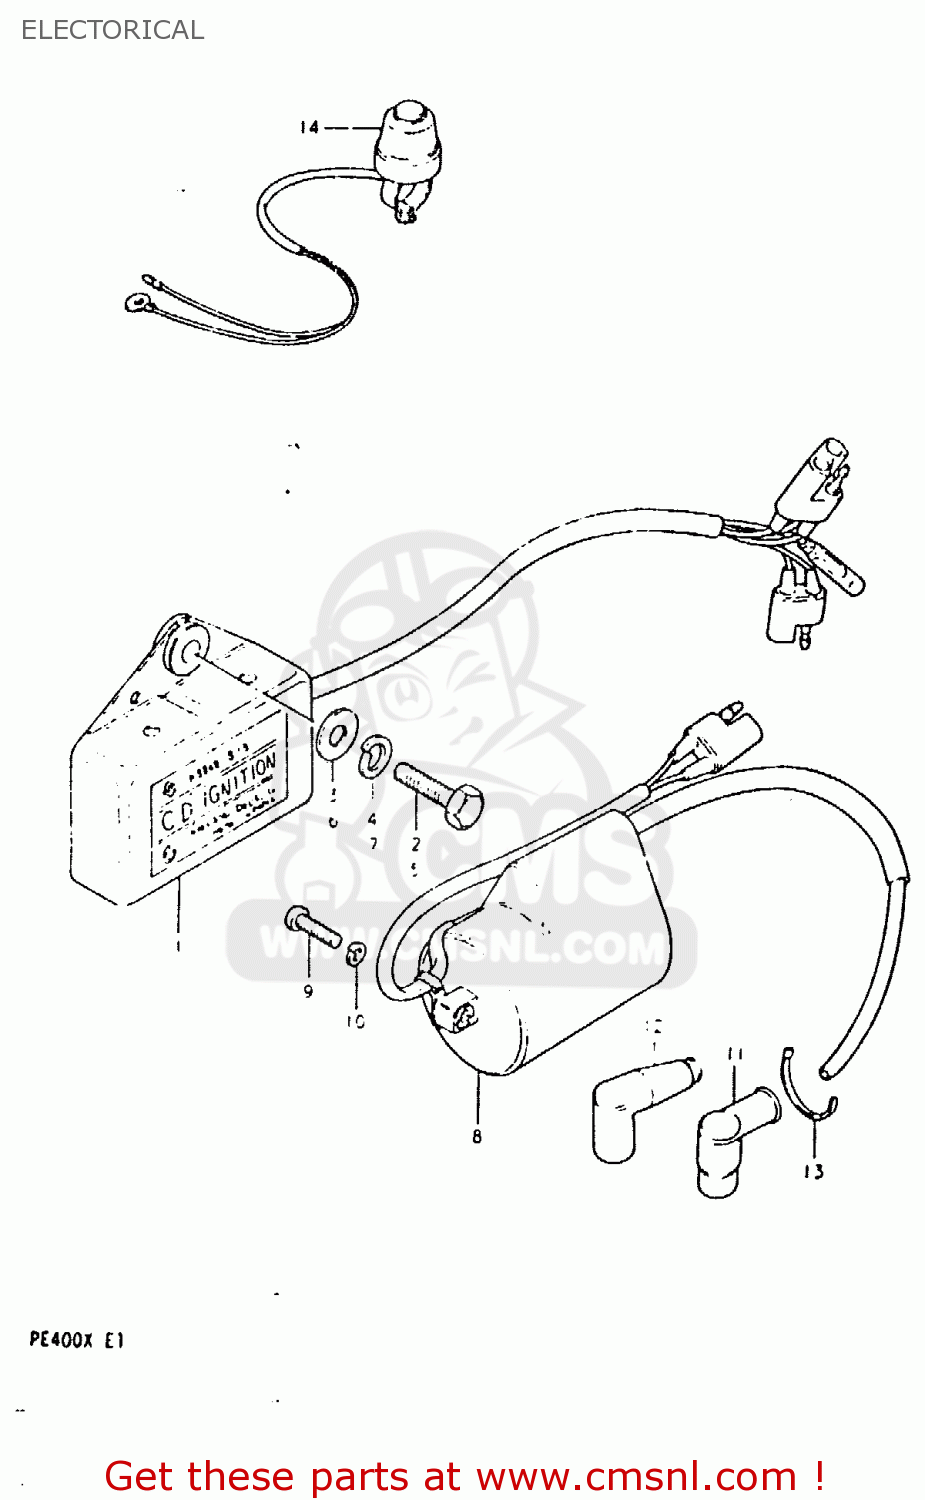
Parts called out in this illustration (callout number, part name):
1	CDI UNIT
5	BOLT 6X22
6	WASHER
7	LOCK WASHER
8	COIL ASSEMBLY,IGNITION
9	SCREW 5X20
10	LOCK WASHER
12	CAP, SPARK PLUG
13	CLAMP
14	SWITCH ASSEMBLY
